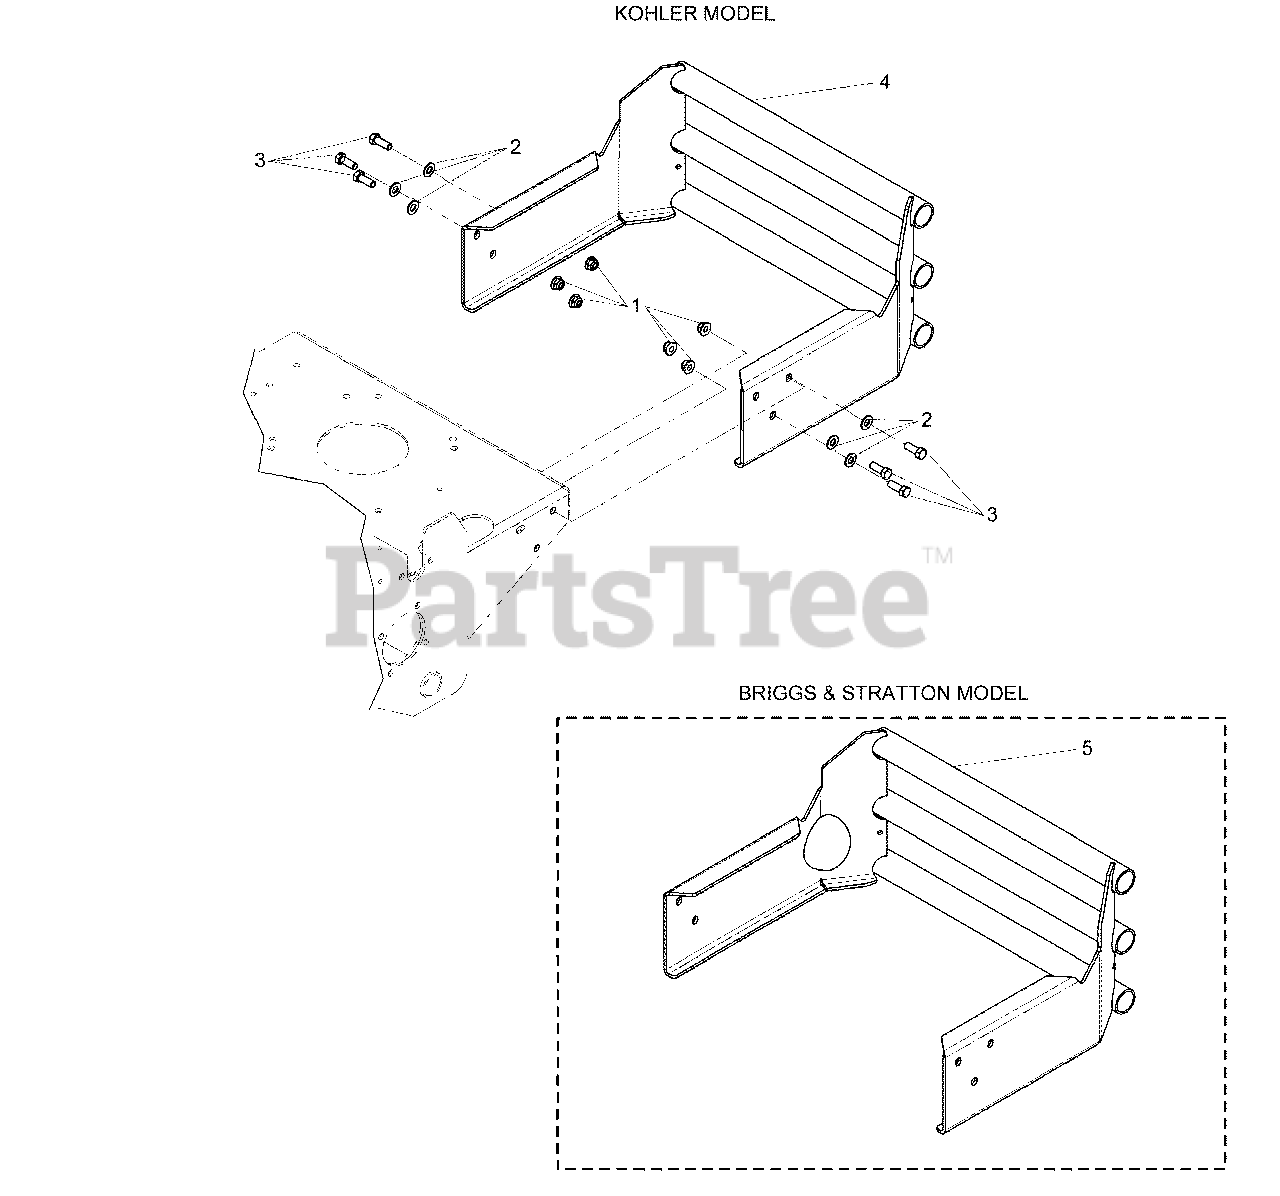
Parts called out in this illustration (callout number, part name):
1	NUT, 3/8-16 HEX NYLOCK FLANGE
2	WASHER 3/8" SAE
3	BOLT, 3/8-16 X 1" GD5
4	WELD, BUMPER
5	WELD, BUMPER
